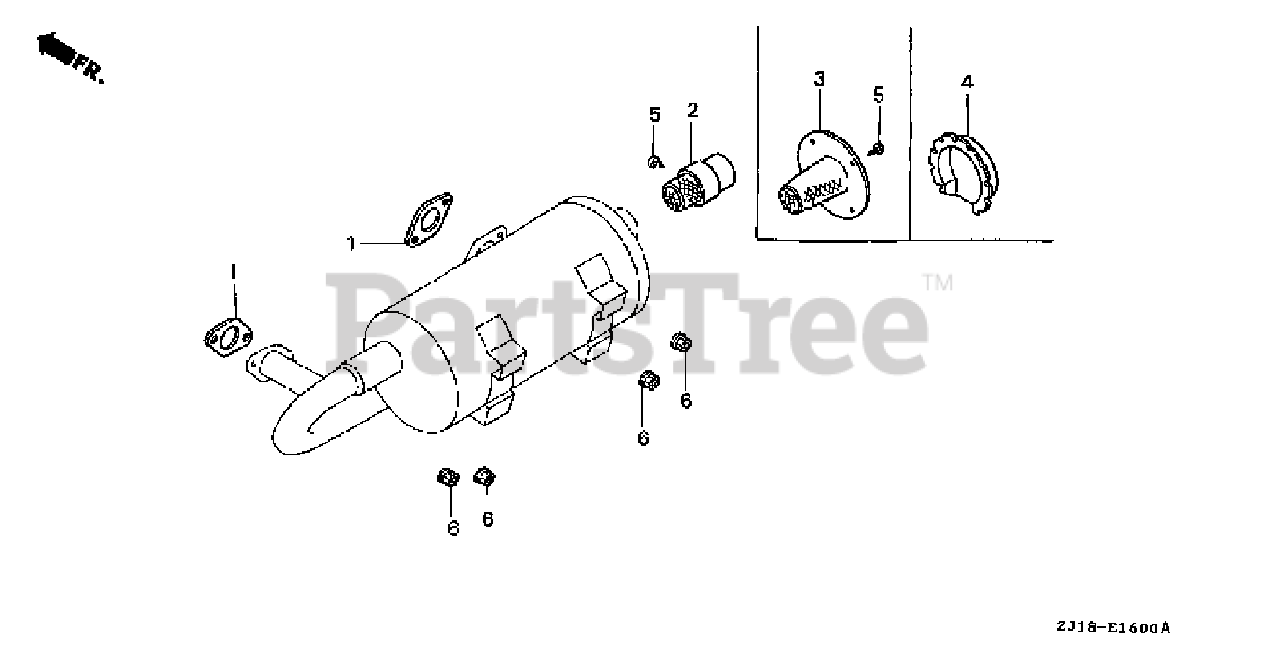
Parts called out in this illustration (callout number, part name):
1	GASKET, EX. PIPE
2	ARRESTER, SPARK
3	ARRESTER, SPARK (SIDE)
4	DEFLECTOR KIT, EX.
5	SCREW (NELSON)
6	NUT, FLANGE (8MM)
